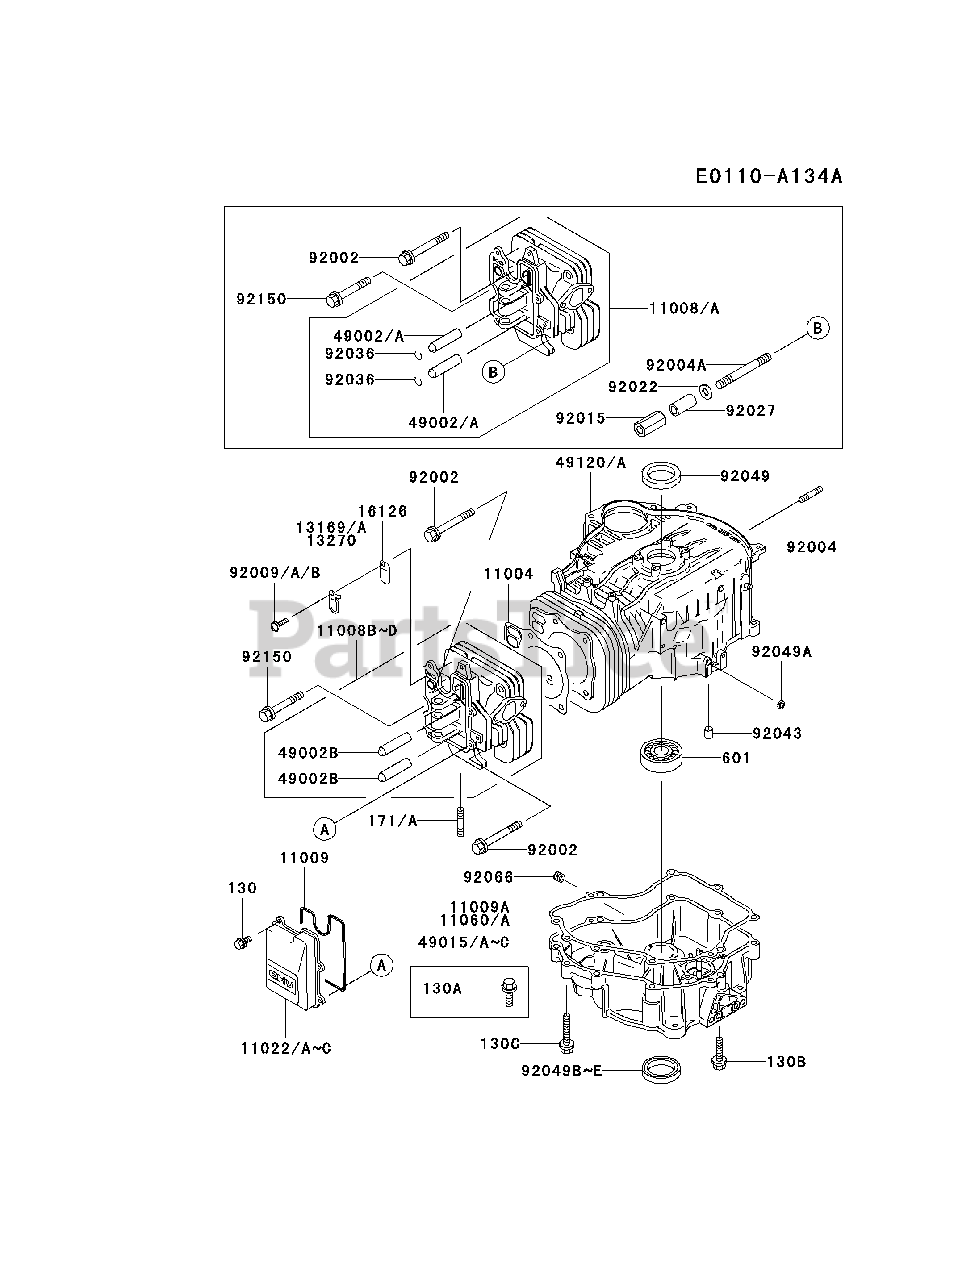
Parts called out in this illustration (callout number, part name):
130	BOLT-FLANGED
130A	BOLT-FLANGED
130B	BOLT-FLANGED
130C	BOLT-FLANGED
171	BOLT-STUD
601	BEARING,BALL
92022	WASHER,10X20X2
